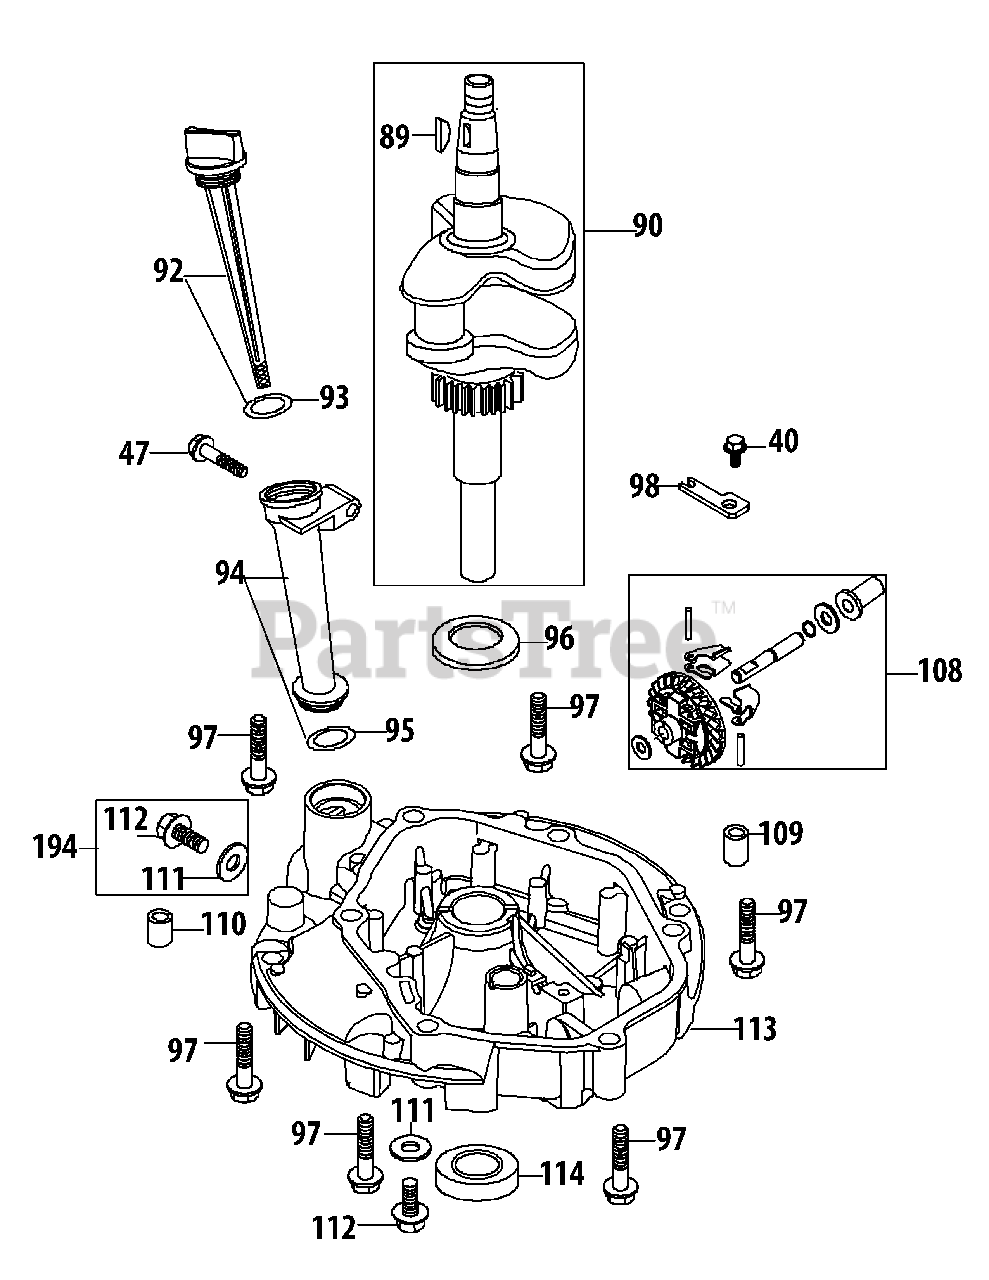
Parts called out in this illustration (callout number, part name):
40	Bolt M6×14
47	Bolt M6×35
89	Woodruff Key
90	Crankshaft Assembly
92	Dipstick Assembly
93	Dipstick O-Ring
94	Oil Filler Tube Assemlby
95	Oil Fill Tube O-Ring
96	Crankshaft Thrust Washer
97	Bolt M8×50
98	Governor Gear Mounting Plate
108	Governor Gear/Shaft Assembly
109	Dowel Pin 7×14
110	Dowel Pin 9×14
111	Oil Drain Plug Washer
112	Oil Drain Plug
113	Crankcase Cover
114	Lower Crankshaft Seal
194	Oil Drain Plug and Washer Assy
